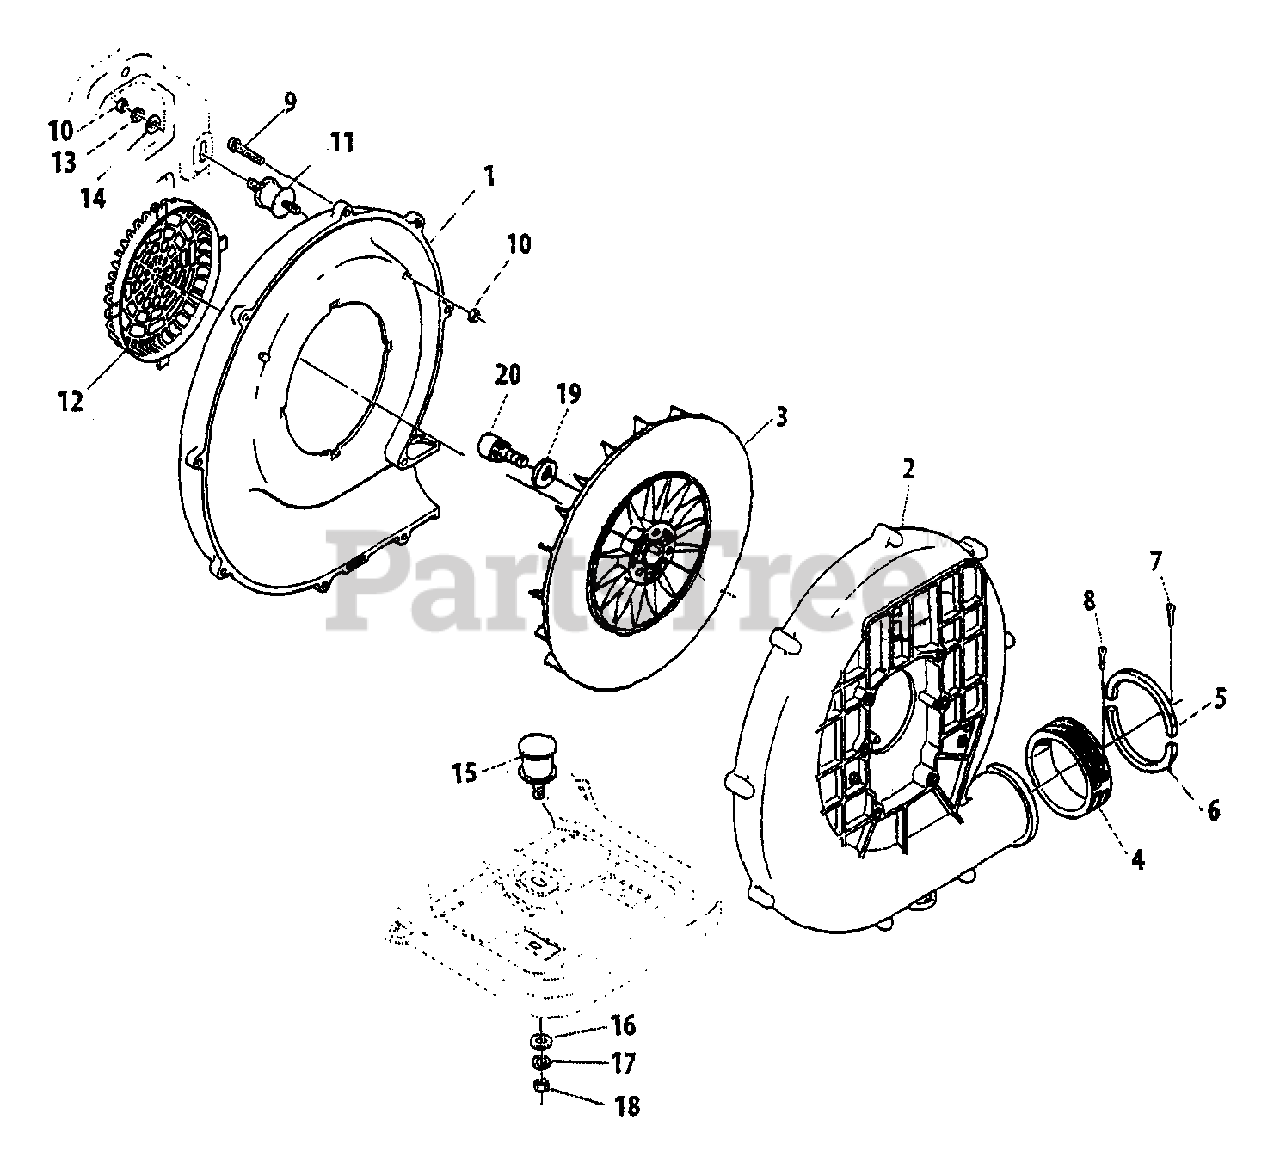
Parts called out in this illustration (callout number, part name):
1	COVER, FAN - INNER
2	COVER, FAN - OUTER
3	IMPELLER
4	SLEEVE
5	RING A
6	RING - B
7	SCREW
8	SCREW -- TAPPING
9	SCREW - 5 -- TAPPING
11	CUSHION
12	COVER, INTAKE
13	LOCKWASHER - 5
14	WASHER
15	CUSHION
17	LOCKWASHER - 6
18	NUT - 6
19	WASHER - 6
20	SCREW - 6X25
